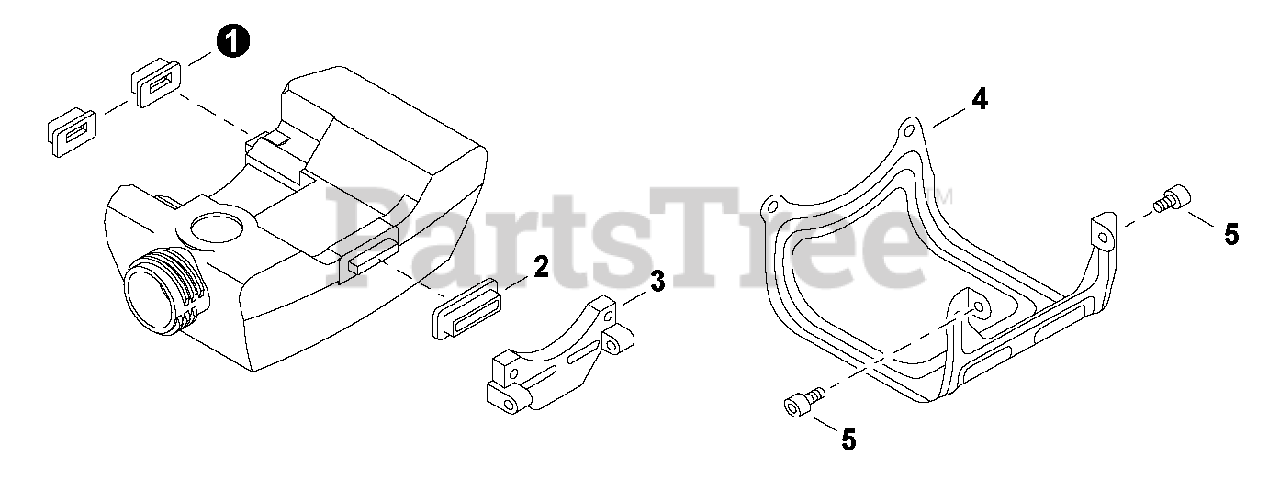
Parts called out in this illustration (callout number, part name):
1	Cushion, Fuel Tank - Front
2	Cushion, Fuel Tank - Rear
3	Bracket, Fuel Tank
4	Guard, Metal Fuel Tank
5	Bolt M5x12
